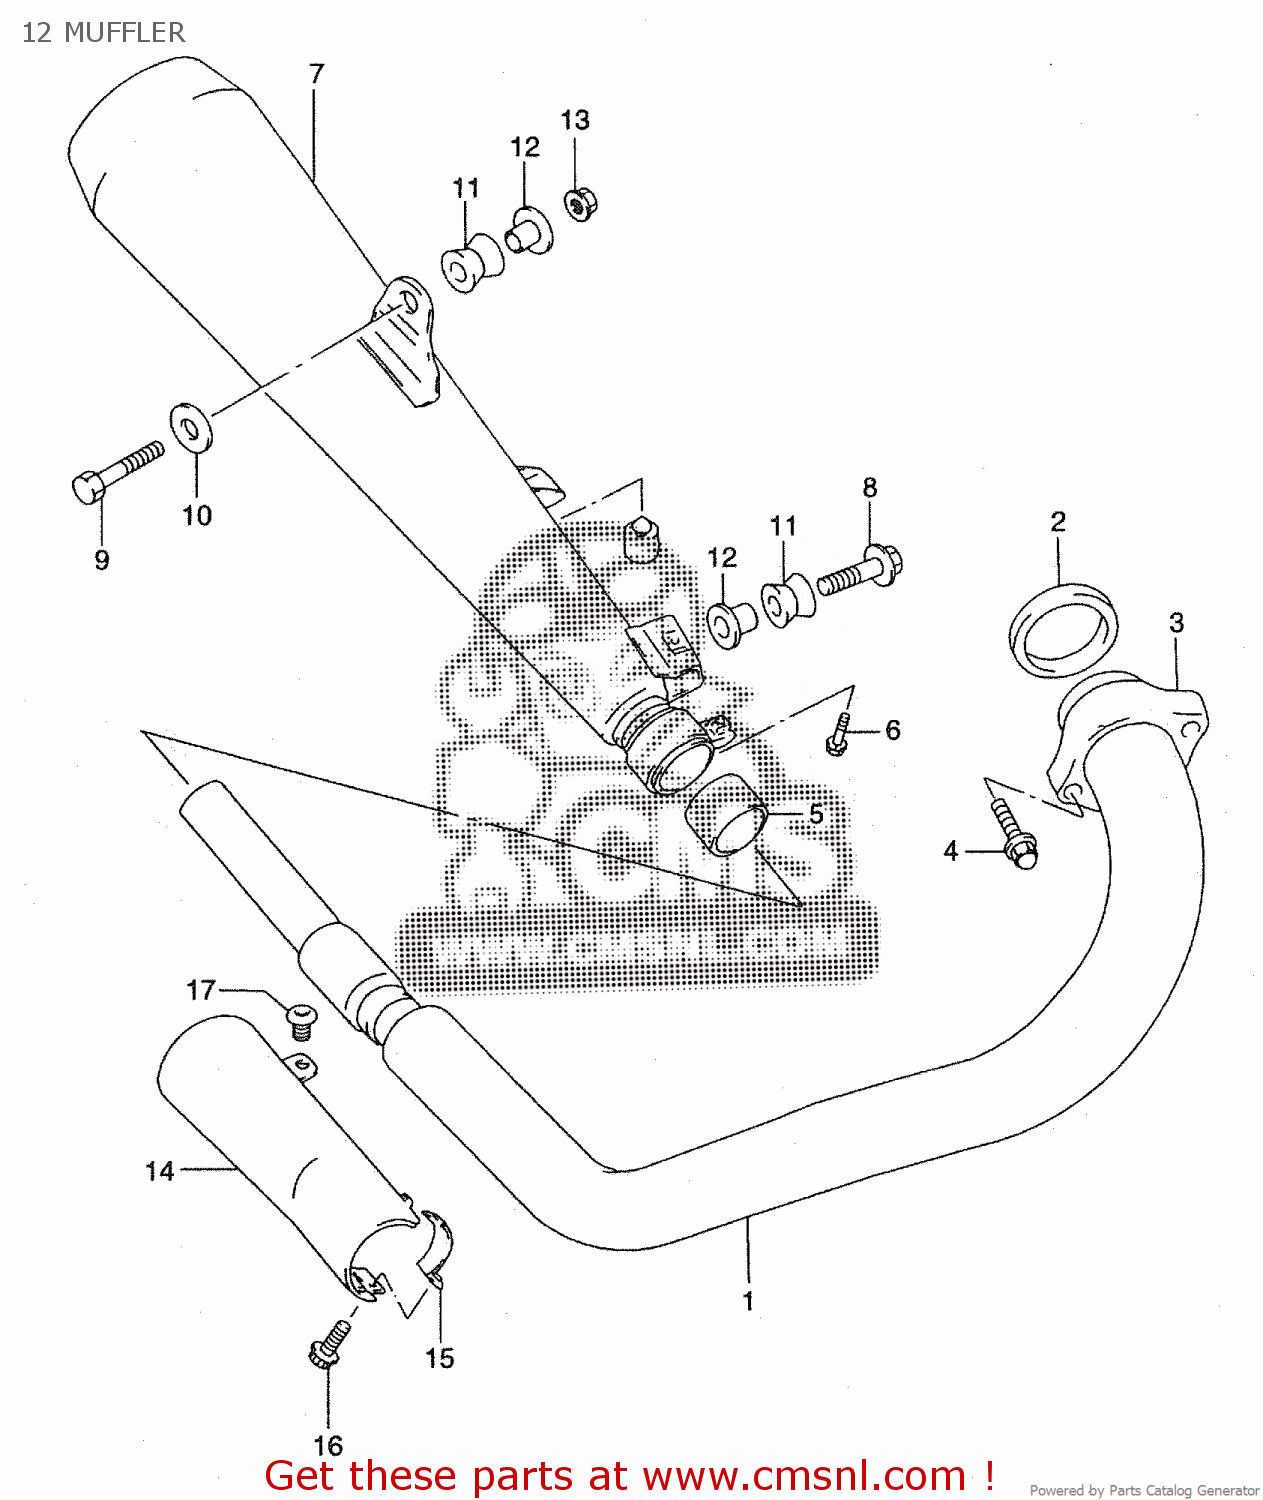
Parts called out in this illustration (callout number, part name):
2	GASKET,EXHAUST PIPE (NAS)
3	CLAMP,EXHAUST PIPE
4	BOLT(8X35)
5	CONNECTOR,MUFFLER
6	BOLT
7	BODY,MUFFLER
8	BOLT(8X35)
9	BOLT
10	WASHER(8.5X28X1.6)
11	CUSHION
12	SPACER(8.6X12X17.5)
13	NUT
14	COVER,MUFFLER
15	CLAMP,EXHAUST PIPE COVER,R RR
16	BOLT
17	SCREW(6X10)
